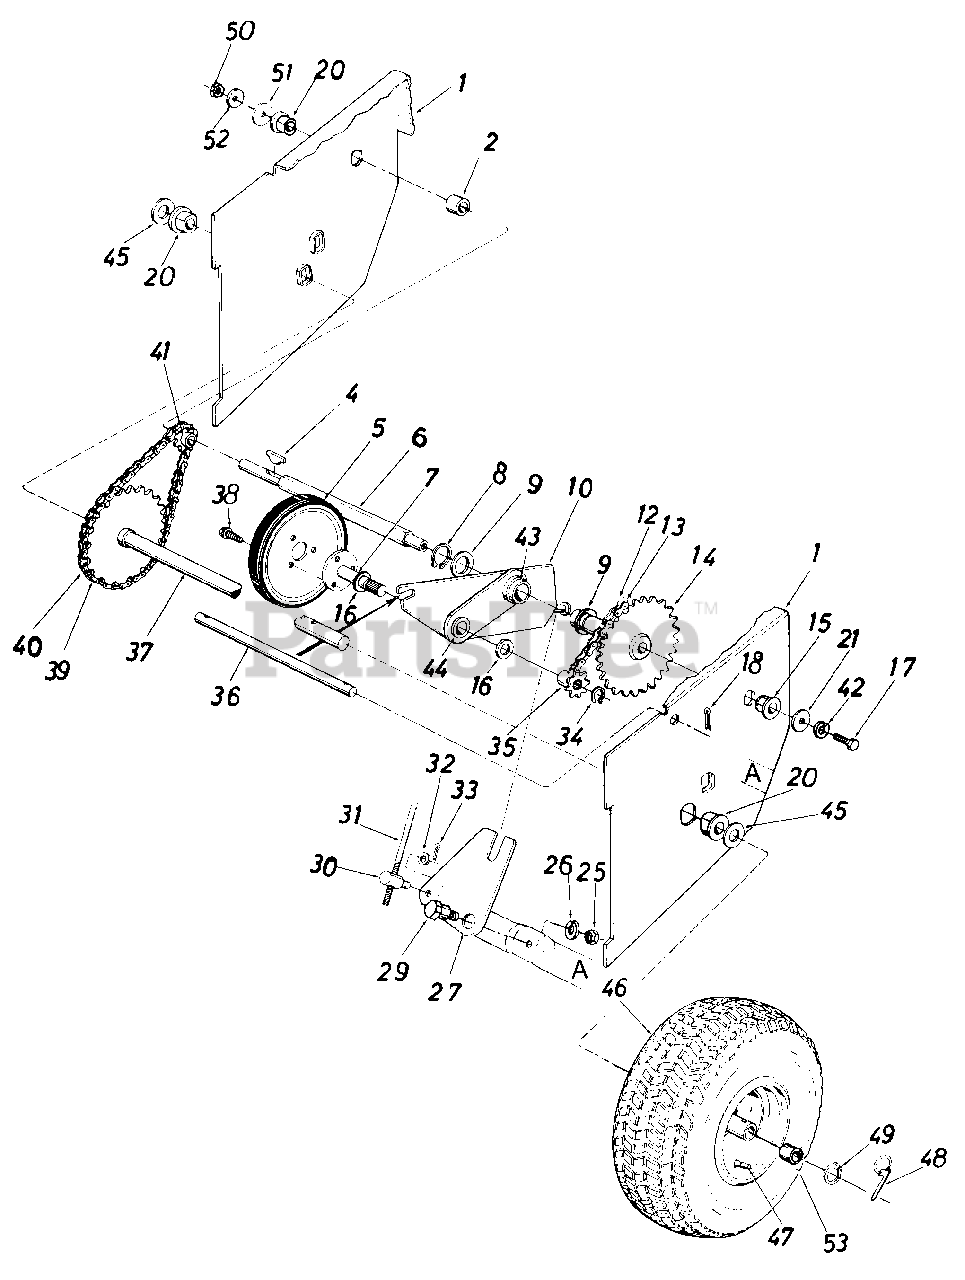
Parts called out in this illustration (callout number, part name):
1	Frame Ass'y.
2	Spacer.50" I.D. x .75" O.D. x.78" Lg.
4	#4 Hi-Pro Key 3/32 x 5/8" Dia.
5	Friction Wheel Ass'y.
7	Friction Wheel Mounting Plate Ass'y.
8	Snap Ring 1.00" Dia. Shaft
9	Fl-Wash. 1.00" x 1.63" O.D. x 03
10	Sliding Bracket Ass'y.
12	#41 Chain 1/2" Pitch x 35 Links
13	Master Link for #41 Chain
14	32 Teeth Sprocket Ass'y.
15	Hex Flange Brg. .630" I.D.
16	Fl-Wash. .62" I.D. x 1.00" O.D. x .06
17	Hex Lock Bolt 5/16-18 x .62" Lg.
18	Cotter Pin 3/32" Dia. x .75" Lg.
20	Flange Brg. w/Flats .75" I.D.
21	Fl-Wash. .34" I.D. x 1.12" O.D. x .125
25	Hex Jam Nut 3/8-16 Thd.
26	L-Wash. 3/8" I.D.
27	Shifting Linkage Bracket
29	Shld. Bolt .625" Dia. x .170" Lg.
30	Adjustment Ferrule
31	Shifting Rod 5/16" Dia. x 32.50" Lg.
32	Fl-Wash. .34" I.D. x .64" O.D. x .06
33	Cotter Pin 3/32" Dia. x .75" Lg.
34	Snap Ring .562" Dia. Shaft
35	Sprocket 7 Teeth x .50" Pitch
36	Shaft .50" Dia. x 9.50" Lg.
37	32 Teeth Wheel Axle Ass'y.
38	Hex Wash. Hd. Self-Tap Scr. 5/16-24 x .50" Lg.
39	#41 Chain 1/2" Pitch x 43 Links (420)
40	Master Link for #41 Chain (420)
41	8 Teeth Center Sprocket
42	L-Wash. 5/16" I.D.
43	Bearing
44	Bronze Bearing
45	Fl-Wash. .76" I.D. x 1.49 O.D.
46	Wheel Assembly
46	Wheel Ass'y. Comp. (420 & 524) 13 x 5.0
47	Air Valve
48	Klick Pin
49	Snap Ring .75 Dia.
50	Hex Ins. L-Nut 1/2-20 Thd.
51	Fl-Wash. .53 I.D. x 1.25 O.D. x . 10
52	Bell-Wash. .50 I.D. x 1.0 O.D. x .075
53	Sleeve Brg.
